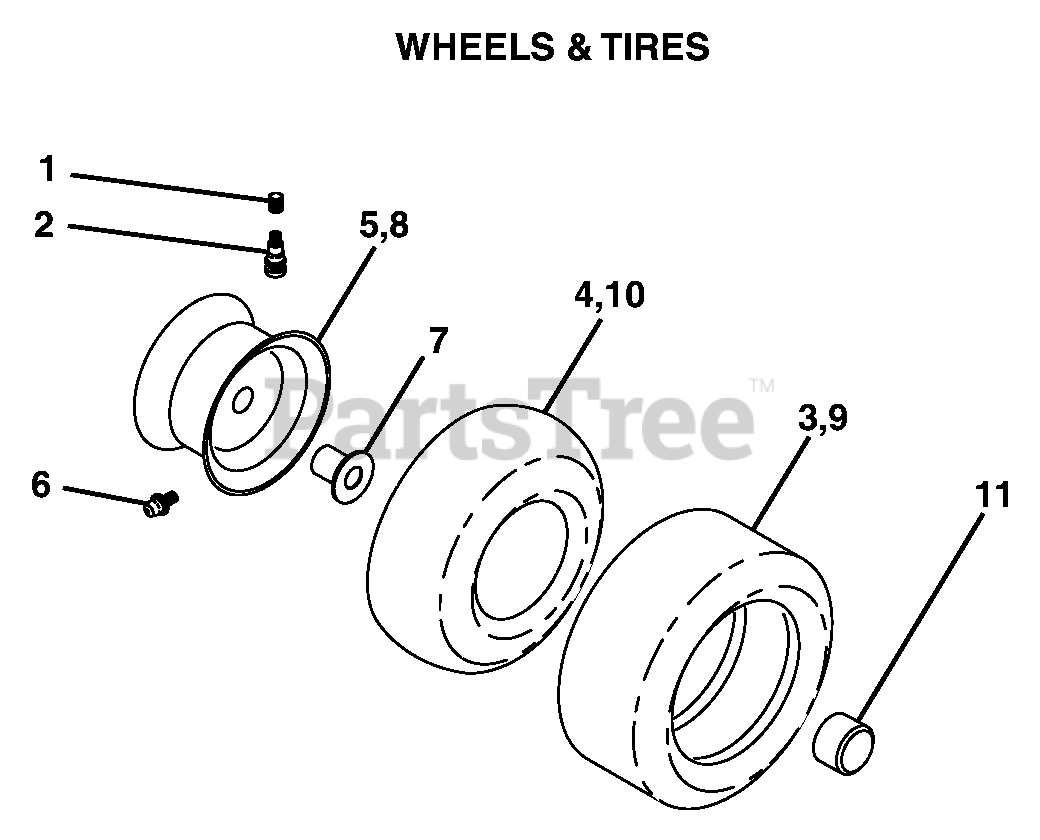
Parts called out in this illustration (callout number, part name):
1	Cap Valve Tire
2	Stem Valve
3	Tire F T 15 x 6 0 - 6 Service
4	Tube Front (Service Item Only)
5	Rim Asm 6" front Service
6	Fitting Grease (Front Wheel Only)
7	Bearing Flange (Front Wheel Only)
8	Rim Asm 8" rear Service
9	Tire R T 20 x 8-8 Service
10	Tube Rear (Service Item Only)
11	Cap Axle Blk 1 50 x 1 00
